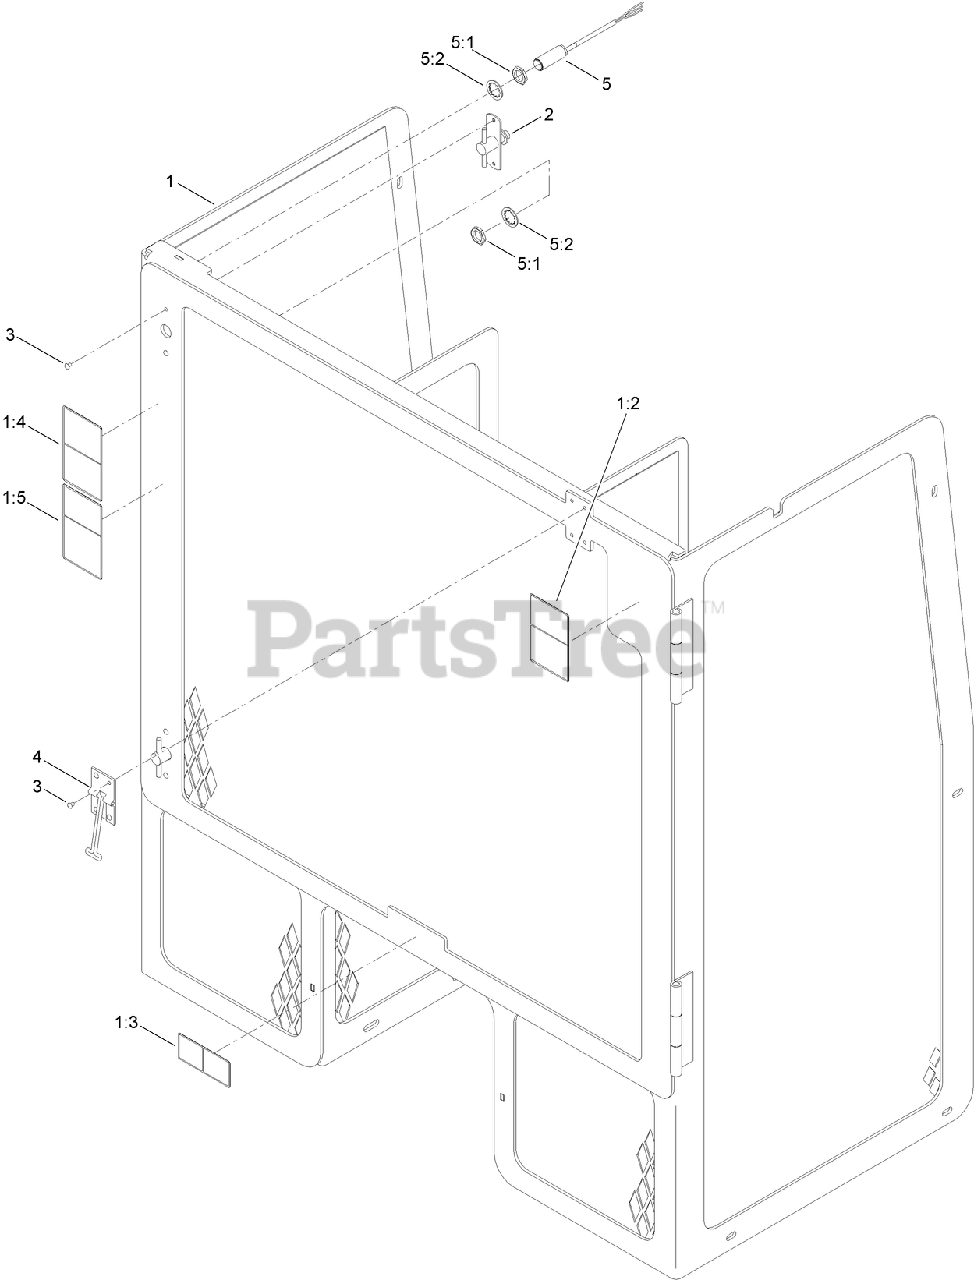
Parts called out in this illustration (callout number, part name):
1	STAKEDOWN CAGE ASM
1:2	DECAL-DANGER, HAZARDOUS AREA
1:3	DECAL-DANGER, ENTANGLEMENT
1:4	DECAL-WARNING, ENTANGLEMENT
1:5	DECAL-DANGER, IMPACT HAZARD
3	RIVET-POP
4	LATCH-RETAINING
5	PROXIMITY SWITCH ASM
5:1	NUT-HEX
5:2	WASHER-LOCK, INTERNAL TOOTH
